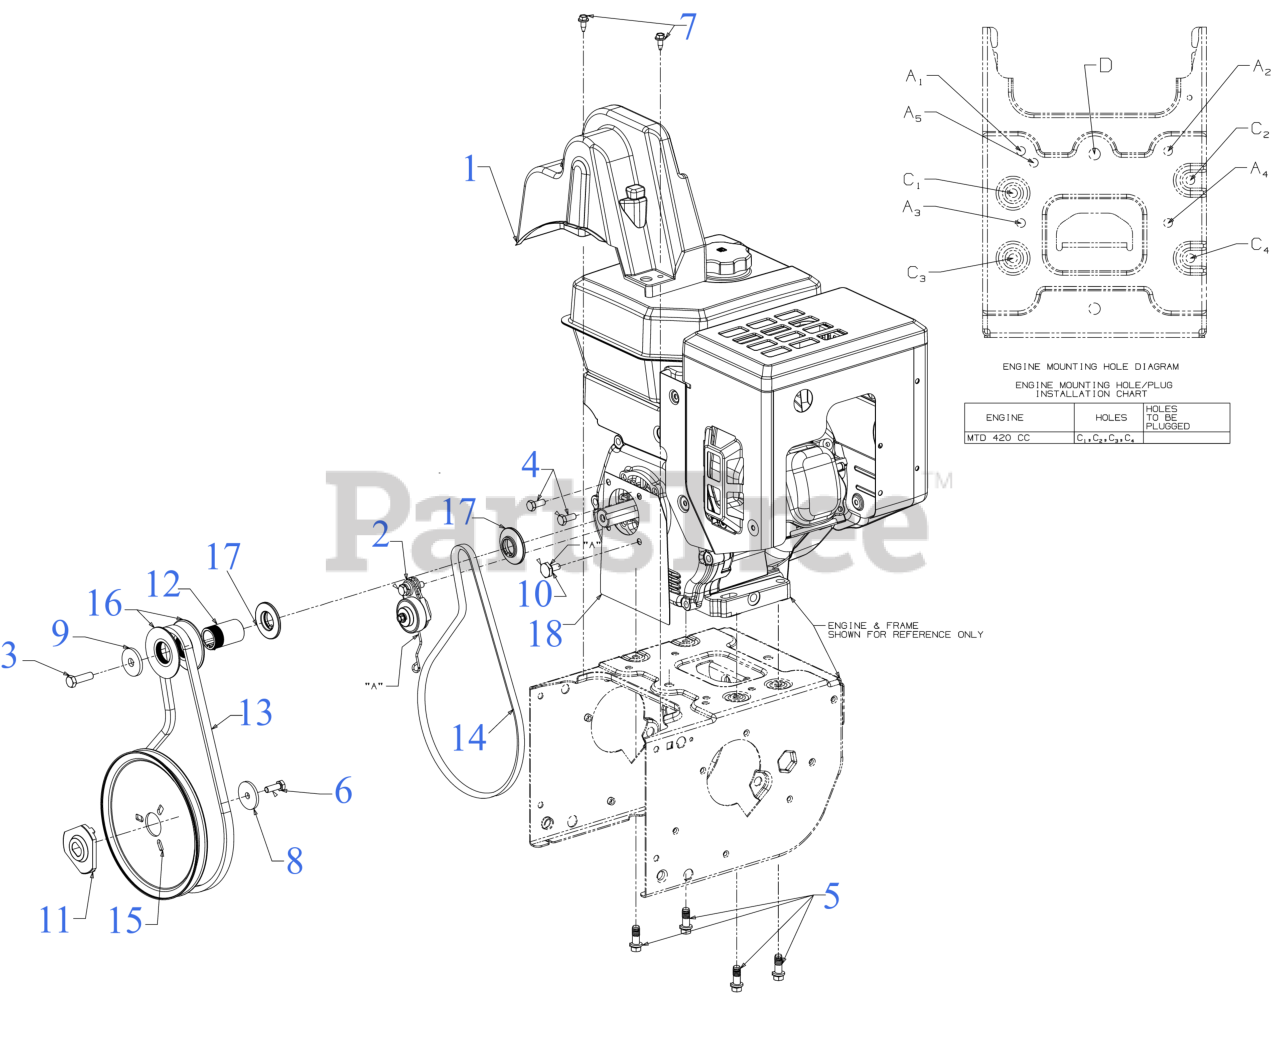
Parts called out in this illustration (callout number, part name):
1	BELT COVER SERVICE KIT (631-05323)
2	IDLER ASSEMBLY
3	SCREW 3/8-24X1.25
4	SCREW 5/16-24 x .750 GR5
5	SCREW 3/8-16 x 1
6	SCREW 5/16-24 x .875 GR5
7	SCREW 1/4-20X.625
8	FLAT WASHER
9	FLAT WASHER .45 x 1.5 x .172 HT
10	SHOULDER SCREW
11	ADAPTER PULLEY .75 DIA W/DD
12	PULLEY SPACER
13	BELT-.500 x 37.00
14	V-BELT 3/8 x 35.68"
15	AUGER PULLEY
16	HALF PULLEY 4L V x 2.6 OD
17	HALF PULLEY-3/8 V x 1.7160
18	ENGINE PLATE (FRONT COVER)
